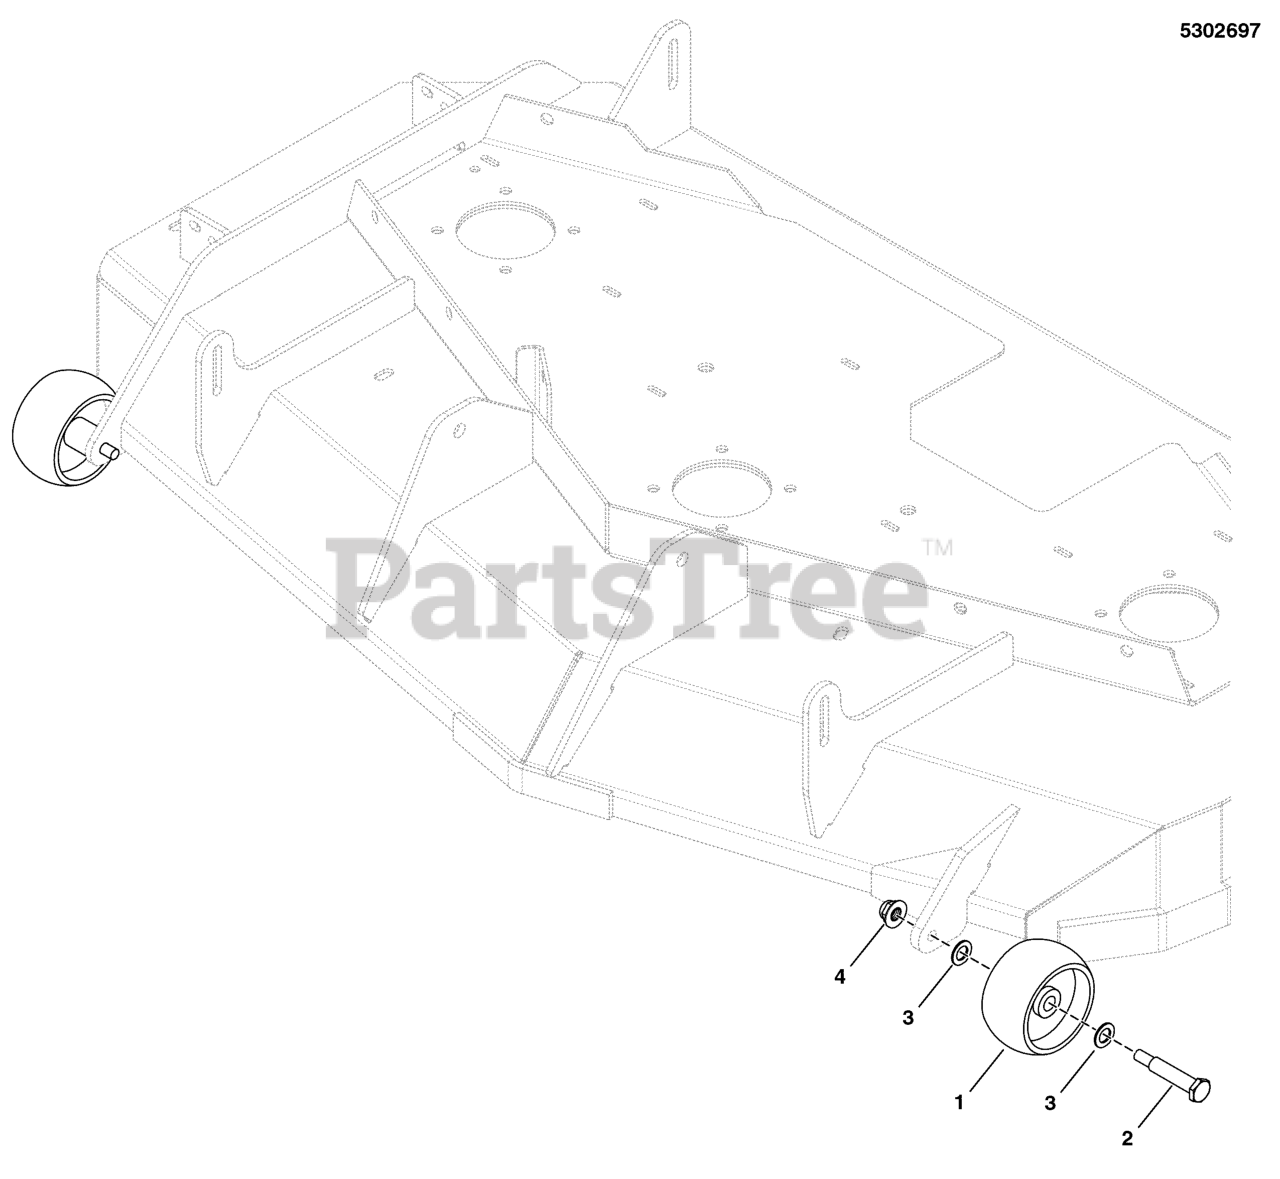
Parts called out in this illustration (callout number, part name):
1	WHEEL- 2.00 WIDE 3.88 DIA 0.531ID POLY
2	BOLT-WHEEL 3/8-16X2.781 .750 THRD
3	WASHER,.516IDX.875ODX.06,FLAT,ZC/CL
4	NUT, 3/8-16 HEX SIDE LOCK
